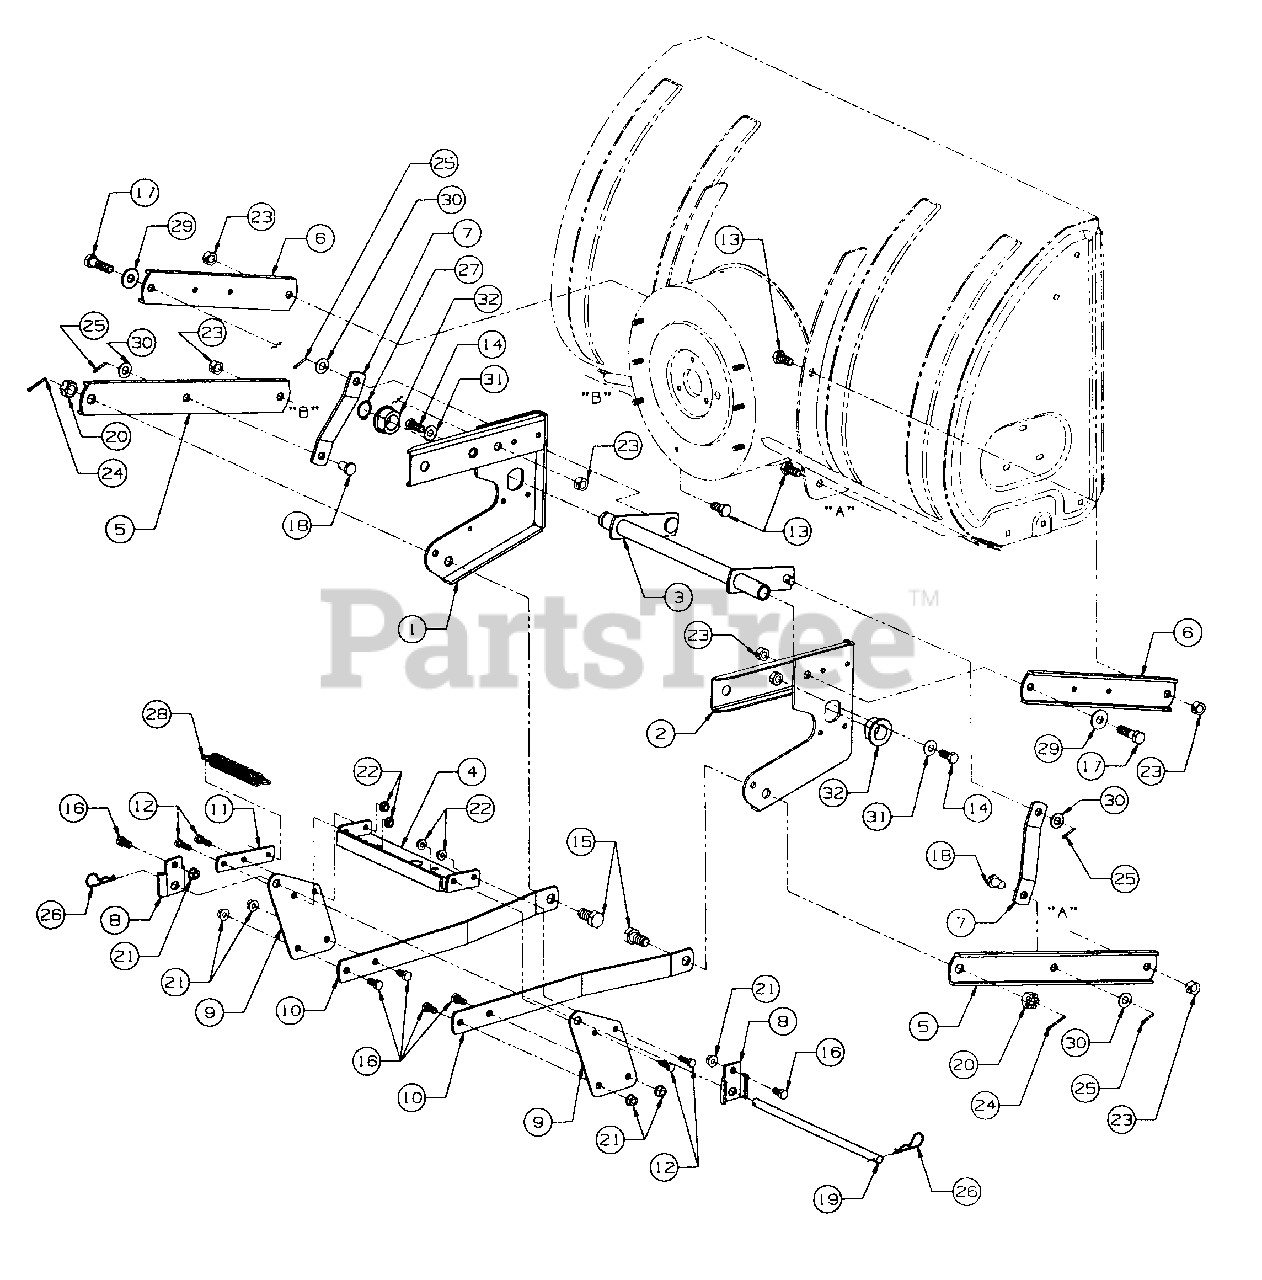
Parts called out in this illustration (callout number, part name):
13	Screw, Hex Cap, 1/2-13 X 1.0 Lg GR2
14	Screw, Hex Cap, 7/16-14 X 1.0 Lg GR5
15	Screw, Hex Cap, 5/8-18 X 1.25 Lg GR5
16	Screw, Hex Cap, 3/8-16 X .75 Lg GR5
17	Screw, Hex Cap, 1/2-13 X 1.75 Lg GR5
18	Pin, Clevis
19	Rod, .50 Dia X 12.50 Lg
20	Nut, Hex Slotted, 5/8-18
21	Nut, Hex Flanged Lock
22	Nut, Hex Flange Top Lock, 5/16-18 GR5
23	Nut, Hex Center Lock, 1/2-13 GR5
24	Pin, Cotter, 1/8 Dia X 1.25 Lg
25	Pin, Cotter, 1/8 Dia X .75 Lg
26	Pin, Internal Cotter
27	Ring, Snap, 1" Dia Shaft
28	Spring, Extension
29	Washer, Flat, .531 X 1.25 X .100 Thk
30	Washer, Flat, .510 X 1.00 X .060 Thk
31	Washer, Bell, .45 X 1.00 X .062 Thk
32	Bearing, Flange
